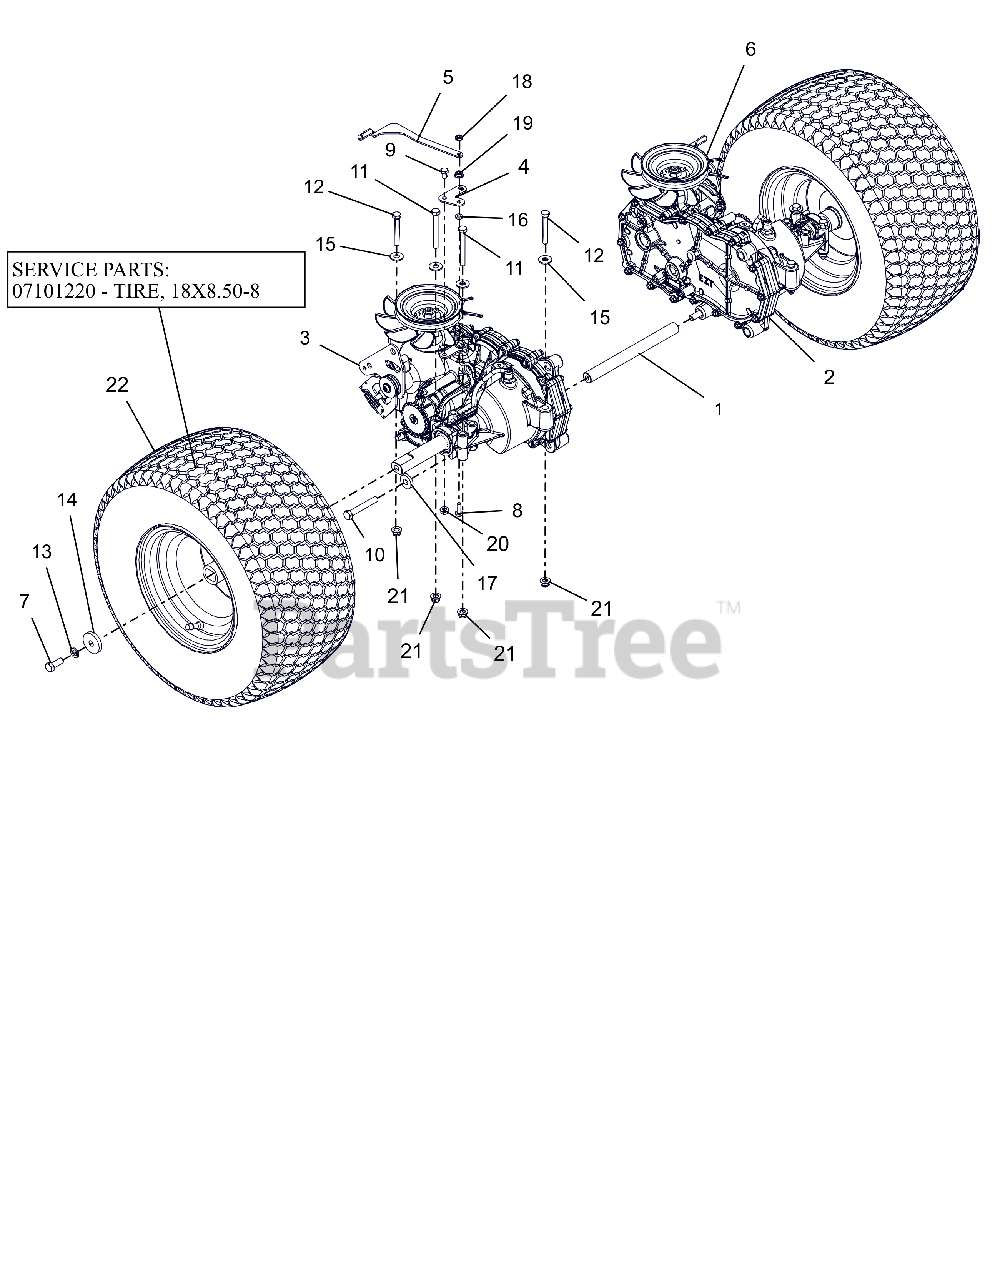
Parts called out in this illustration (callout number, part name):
1	ROD, TRANSAXLE BRACE
2	TRANSAXLE,LH EZT D-SHFT SHORT
3	TRANSAXLE,RH EZT D-SHFT SHORT
4	BRKT, DUMP VALVE EXTENSION
5	BRKT, DUMP VALVE RH
6	BRKT, DUMP VALVE LH
7	BLT-HEX .38-16X1.0 GR8 YZ EP30
8	@BLT-HEX .25-20X.75 GR5 YWZC
9	@BLT-HEX .25-20X.50 GR5 YWZC
10	@BLT-HEX .38-16X2.50 GR5 YWZC
11	@BLT-HEX .31-18X2.75 GR5 YWZC
12	@BLT-HEX .31-18X2.25 GR5 YWZC
13	@WSHR-LK .38X.094 REG YWZC
14	WSHR,FLT STL.406X1.50X.245YWZC
15	@WSHR-FL-STL.38X.875X.083 YWZC
16	WSHR-FL-STL .265X.50X.087YWZC
17	WSHR-FL-STL .406X1.00X.188 YWZ
18	NUT-LK-CTR JAM .25-20 YWZC
19	@NUT-SPNLK-FLG .25-20 YWZC
20	@NUT-LK-TOP-FLG .25-20 YWZC
21	@NUT-LK-NYL-FLG .31-18 YWZC
22	ASM, WHL/TIRE 18X8.50-8 DHUB
22	TIRE, 18X8.50-8
22	TUBE 18X9.50-8
